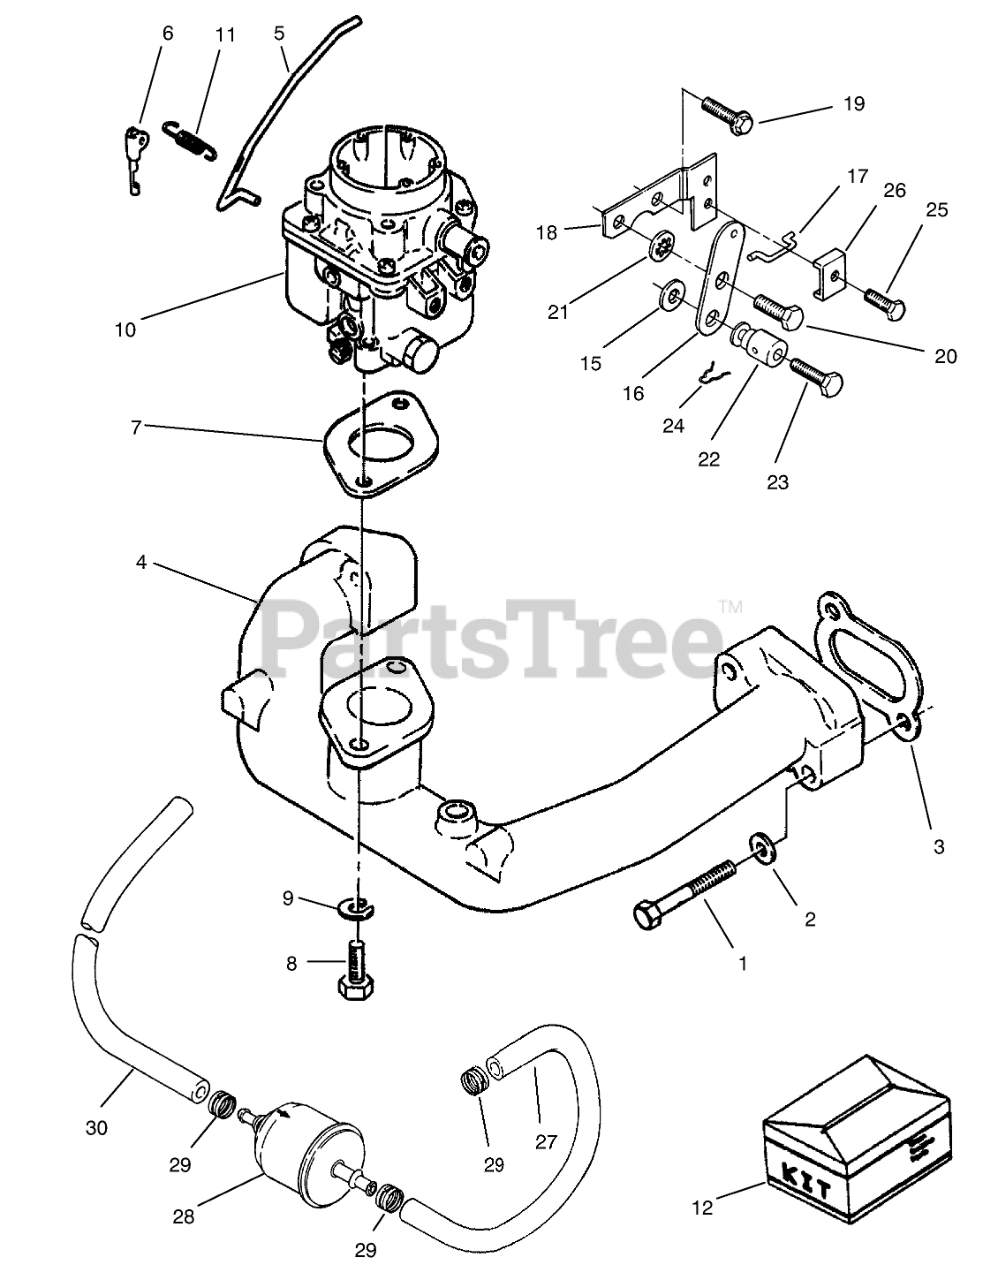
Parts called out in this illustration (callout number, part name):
2	Nut-M8
3	Gasket
4	INTAKE-MANIFOLD
5	GOVERNOR-CONTROL ROD
6	CONTROL-ROD CLIP
7	Gasket
8	HEX-HEAD CAP SCREW
9	Washer
10	COMPLETE-CARBURETOR
11	SPRING
12	Kit-Repair
15	Washer
16	SWIVEL-CHOKE
17	LINK-CHOKE
18	BRACKET
19	Bolt
20	BOLT-SHOULDER
21	Lockwasher
22	SWIVEL
23	Bolt
24	PIN-COTTER
25	Bolt
27	Hose
28	Filter-Fuel
29	Clamp
30	Hose
